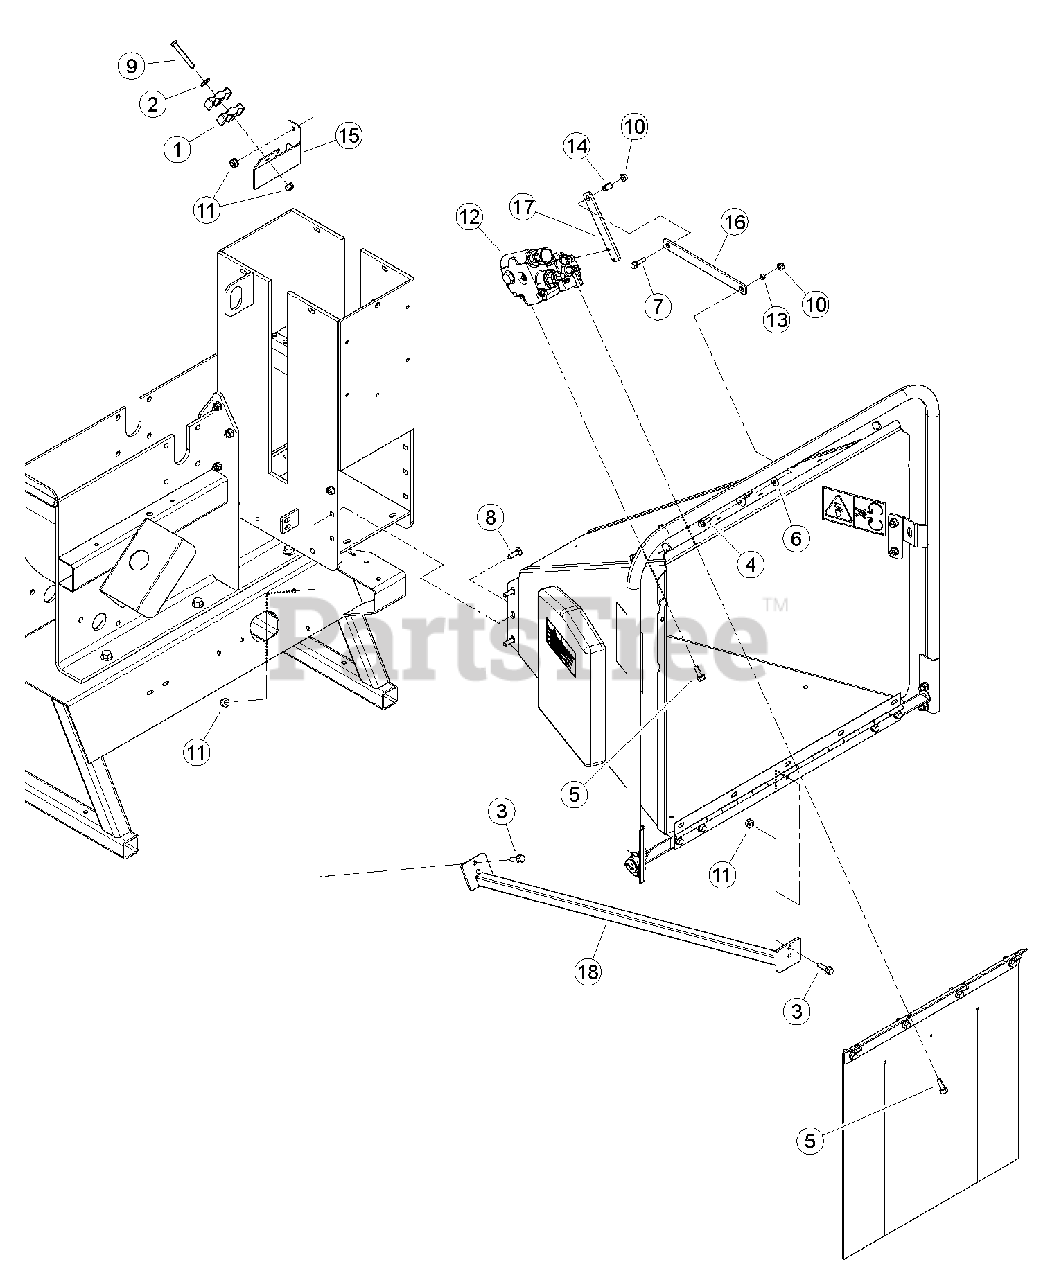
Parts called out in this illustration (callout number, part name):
1	CLAMP, PLASTIC HOSE
2	WASHER, 3/8 FLAT
3	BOLT, 3/8 X 1-1/4 FLANGE NC
4	BOLT, 5/16 X 1 FLANGE NC
5	BOLT, 3/8 X 1 FLANGE NC
6	WASHER, 5/16 FLAT
7	BOLT, 5/16 X 1-1/4 FLANGE NC
8	BOLT, 3/8-16 X 1-1/4 GR5 CRG
9	BOLT, 3/8 X 2-3/4" GR5 NC HHCS ZP
10	NUT, 5/16-18 NYLOCK FLANGE
11	NUT, 3/8-16 NYLOCK FLANGE
12	VALVE, 4-WAY 4-POSITION FC & RELIEF
13	SPACER, IDLER PIVOT
14	SPACER, .50 X .775
15	WELDMENT, HOSE BRACKET
16	LEVER, VALVE CONTROL
17	LINK, VALVE CONTROL
18	WELDMENT, CHUTE SUPPORT
